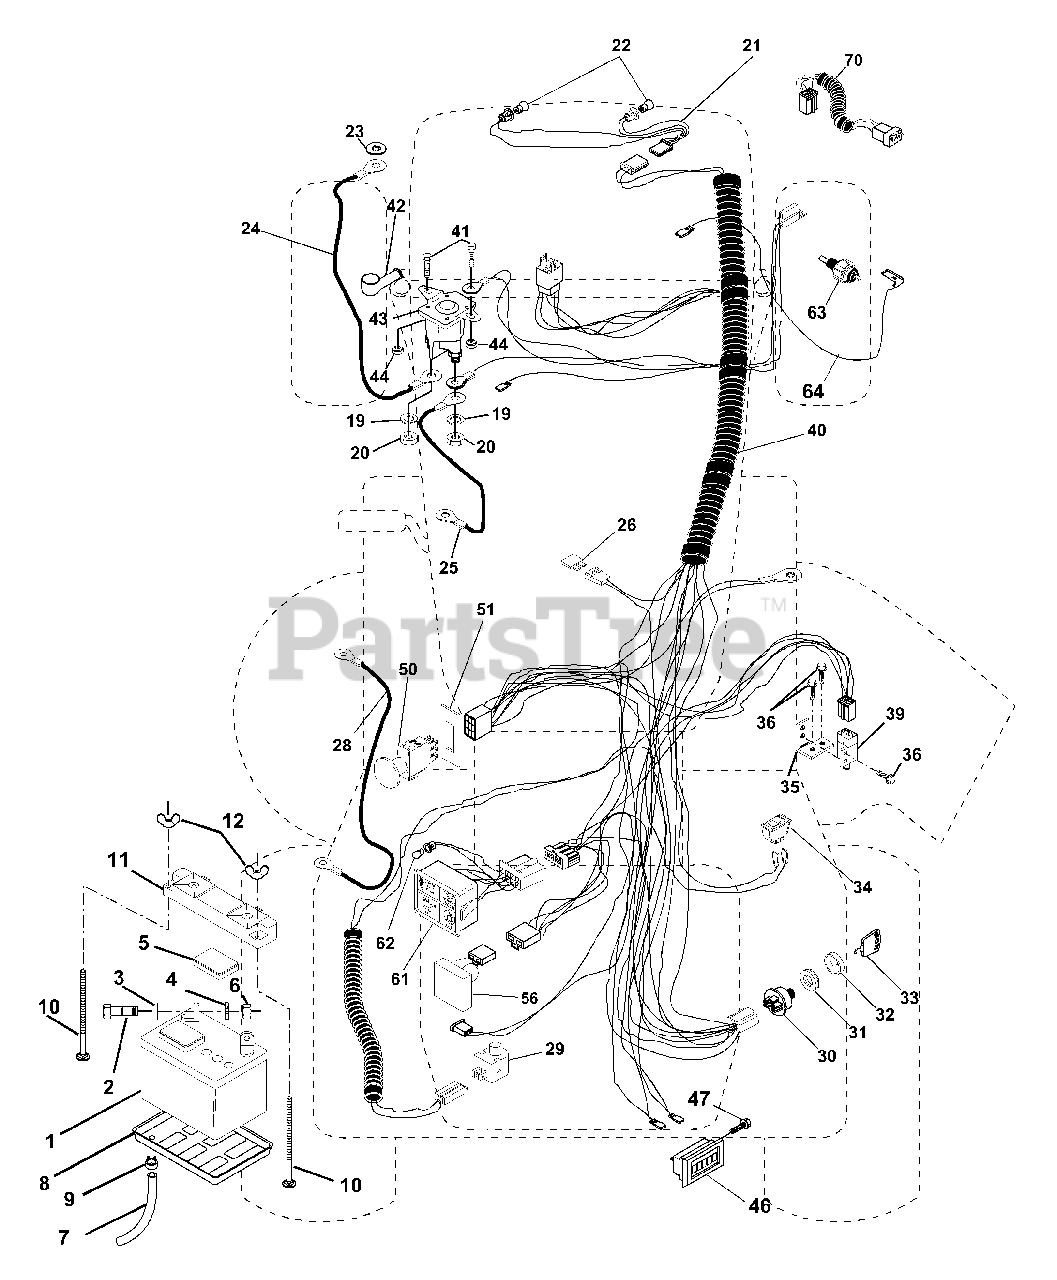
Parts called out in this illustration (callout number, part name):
1	Battery
2	Bolt, Hex Head 1/4-20 x 3/4
3	Washer 9/32 x 5/8 x 16 Gauge
4	Washer, Lock 1/4
5	Caps, Battery
6	Nut, Hex 1/4-20
7	Tube, Tray, Battery
8	Tray, Battery
9	Clamp, Hose
10	Bolt, Carriage 1/4-20 x 7-1/2
11	Guard, Terminal
12	Nut, Wing 1/4-20
19	Washer, Lock 1/4
20	Nut, Hex, Jam 1/4-20
21	Harness, Socket, Light
22	Bulb, Light
23	Washer, Lock, Internal Tooth 1/4
24	Cable, Starter, 6 Ga 11" Red
25	Cable, Battery
28	Cable, Battery
29	Switch, Plunger
30	Switch, Ignition
31	Nut, Ignition
32	Cover, Switch, Ignition
33	Key, Molded
34	Switch, Light
35	Bracket Switch Interlock
36	Screw, Hex Tap #10-24 UNC
39	Switch, Interlock (4 Terminal)
40	Harness, Ignition
41	Bolt, Hex1/4-20 x 1/2 Grade 5
42	Cover, Terminal
43	Solenoid
44	Nut, Hex, Keps 1/4-20
46	Meter, Hour
47	Screw #10-24 x 1/2
50	Switch, P.T.O.
51	Ring, Retainer, Pto
56	Sensor, Low Voltage
61	Package, Light
62	Bulb, Light Package
63	Switch, Oil Sensor
64	Wire, Lead, Sentry, Kohler
70	Harness, Engine
